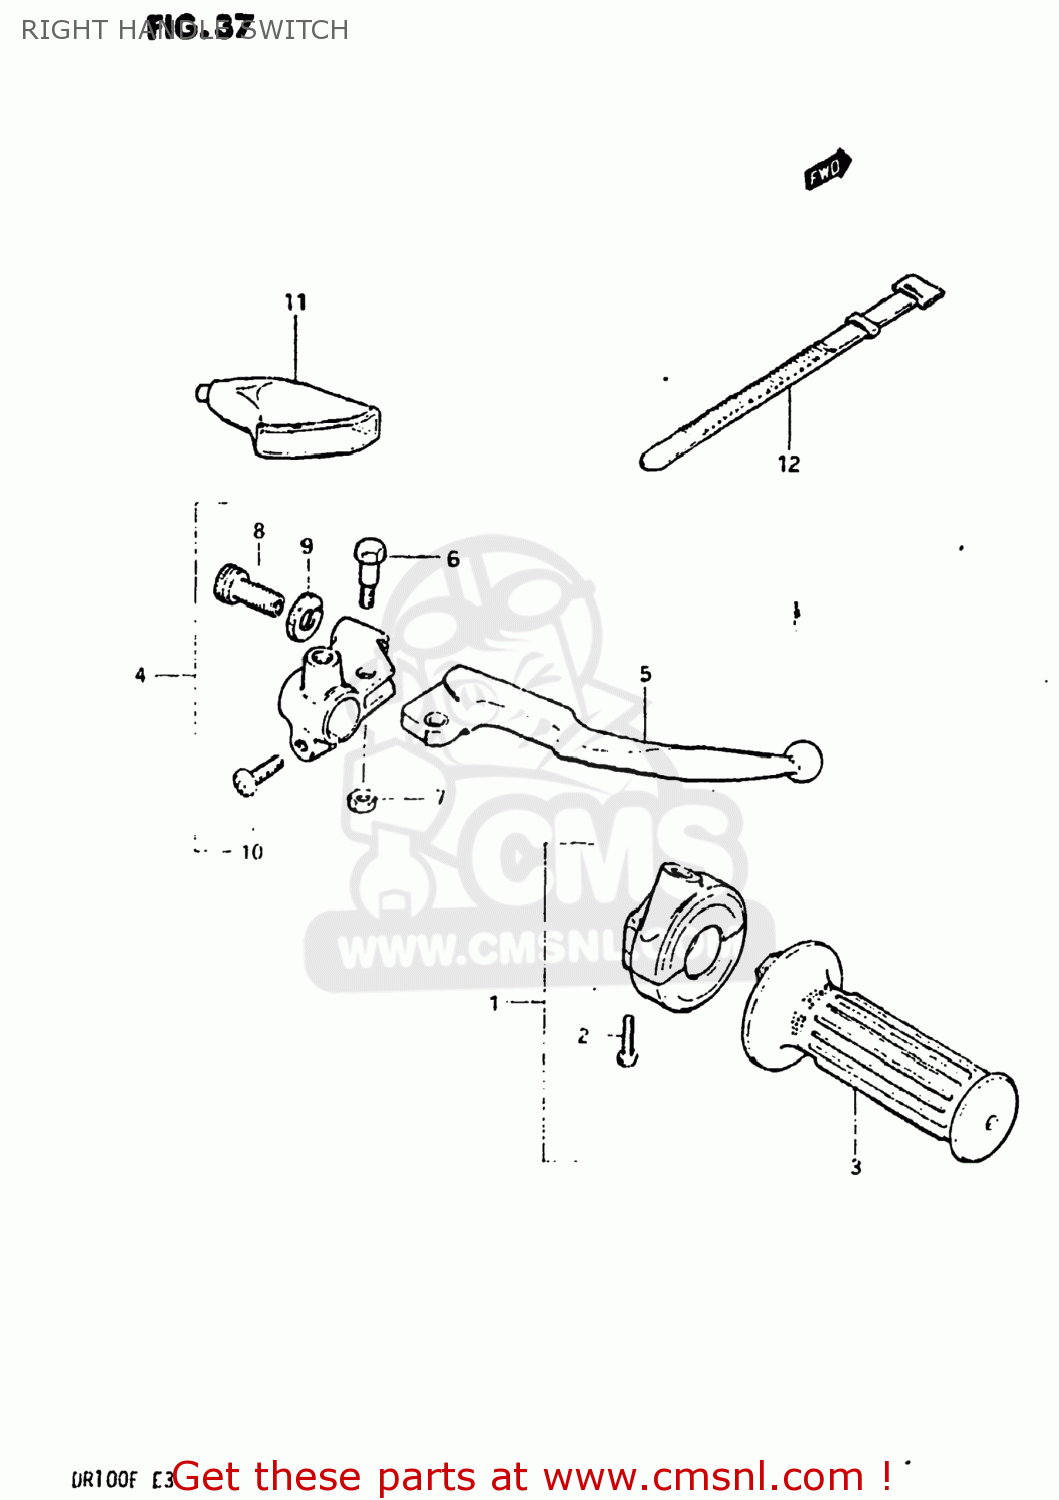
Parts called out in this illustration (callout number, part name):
1	CASE ASSY,THROTTLE
2	SCREW 5X20
3	GRIP,THROTTLE
4	LEVER ASSEMBLY,BRAKE
5	LEVER,BRAKE
6	BOLT,LEVER
7	NUT 6MM
8	ADJUSTER,CABLE
9	NUT,CABLE ADJUSTER
10	SCREW
11	COVER,CLUTCH LEVER
12	CLAMP(L:120)
